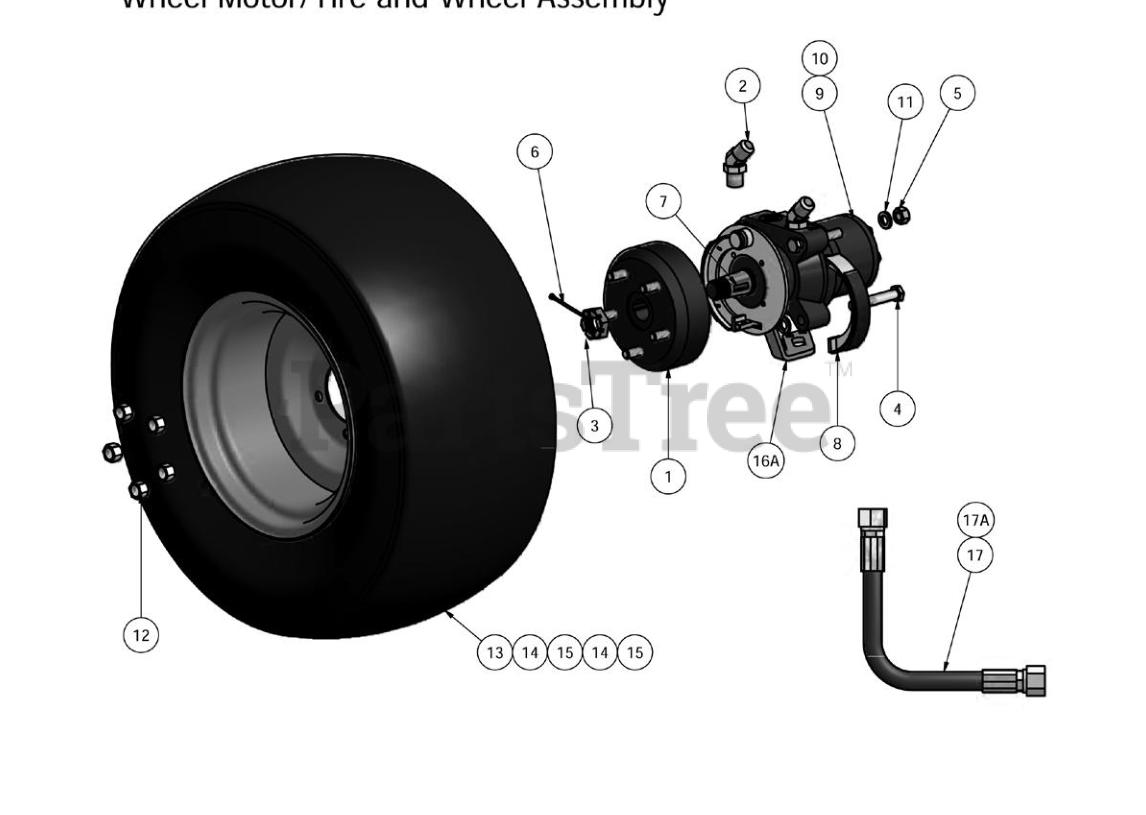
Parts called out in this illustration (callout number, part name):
1	Brake Drum
2	Hydraulic Fitting
3	Castle Nut
4	1/2" 13 x 3" GRS Hex Bolt Zinc
5	1/2" Hex Nut
6	1/8"x2 1/4" Cotter Pin
7	Woodruff Key
8	Brake Shoe
9	Wheel Motor and Drum Brake Combo-18E Right
10	Wheel Motor and Drum Brake Combo-18E Left
11	1/2" Lock Washer
14	24" x 12-12 Tire (Compact Diesel)
15	24" Tire and Wheel Assembly
16	Brake Lever (wheel motor) Left
16A	Brake Lever (wheel motor) Right (Shown)
17	Hydraulic Hose
17A	26" Hydraulic Hose (Compact Diesel)
